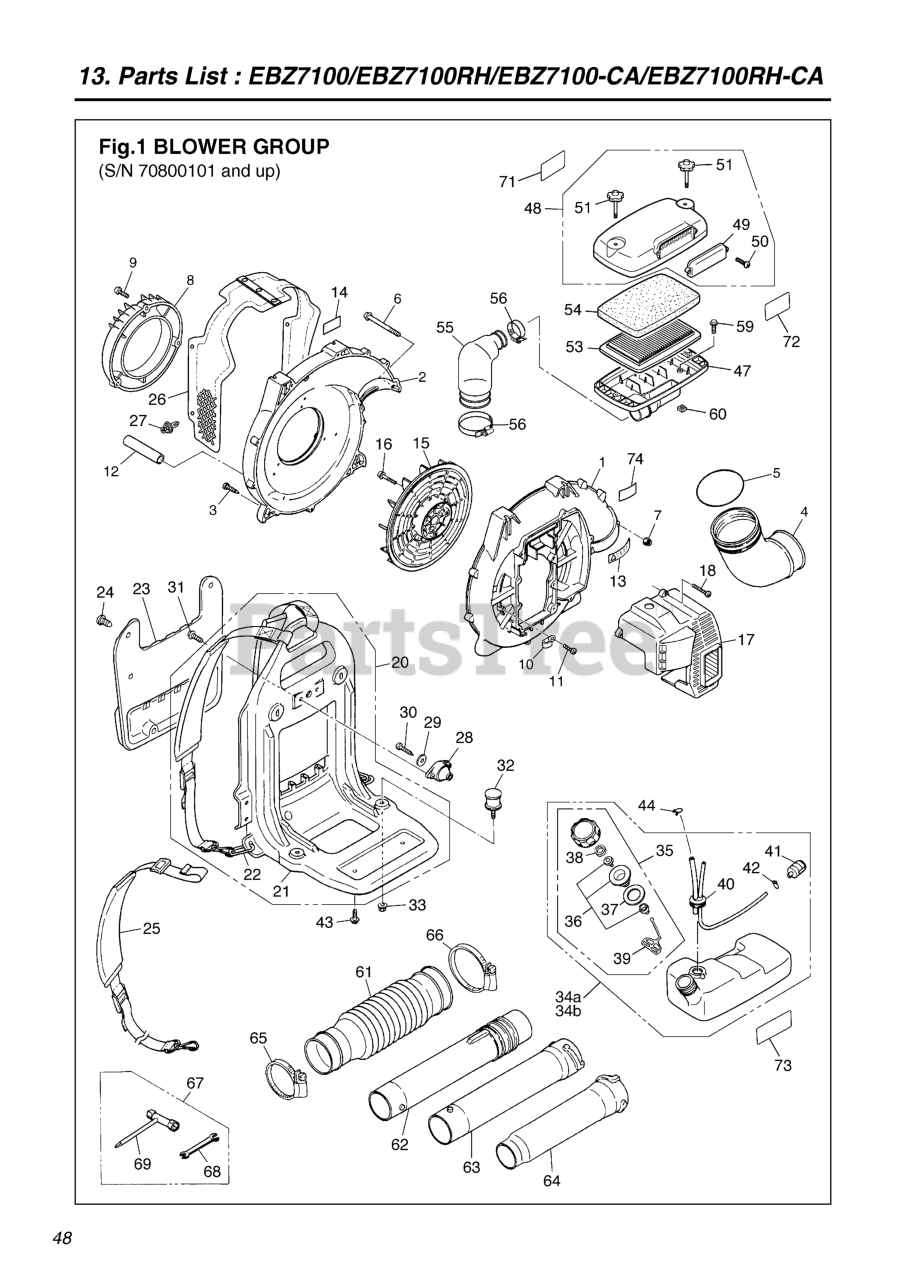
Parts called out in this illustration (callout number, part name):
1	VOLUTE CASE
2	VOLUTE COVER RPLS 848L5C55B3
3	SCREW
4	ELBOW
5	O-RING
6	SCREW TORX
7	NUT (B)
8	COVER, INLET
9	SCREW
10	CLAMP
12	TUBE (RPLS. 07270-01507)
13	LABEL, CAUTION (RPLS -31910)
14	LABEL, NET
15	FAN
16	BOLT
17	ENGINE COVER
18	SCREW
20	FRAME ASSY
21	FRAME COMP
22	RING (REPLACES -21120)
23	PAD
24	CLIP (RPLS 3490-21320)
25	BAND ASSY
26	NET COMP
27	CLIP
28	DAMPER, UPPER
29	WASHER
30	BOLT, TORX
31	SCREW TORX
32	DAMPER, LOWER
33	NUT, M6
34A	TANK ASSY (RPLS. -85100)
35	CAP ASSY
36	HOLDER (REPLACES -85230)
37	PACKING
38	FILTER
40	PIPE COMPLETE
41	FILTER ASSY
42	CLIP (REPLACES 2841-31280)
43	SCREW TORX
44	CLIP
47	BODY, CLEANER
48	COVER ASSY
49	COVER
50	SCREW
51	KNOB BOLT (RPLS T4012-82800)
53	ELEMENT PAPER (RPLS T401282310)
54	ELEMENT (FOAM) (RPLS -82320)
55	HOSE
56	CLAMP
60	NUT
61	HOSE
62	SWIVEL JOINT
63	PIPE, STRAIGHT
64	PIPE, END
65	CLAMP
66	CLAMP
67	TOOL-SET
68	SPANNER, 8 x 10 (RP 090100810)
71	LABEL
72	LABEL, CLEANER
73	LABEL, TANK
74	LABEL, SOUND
